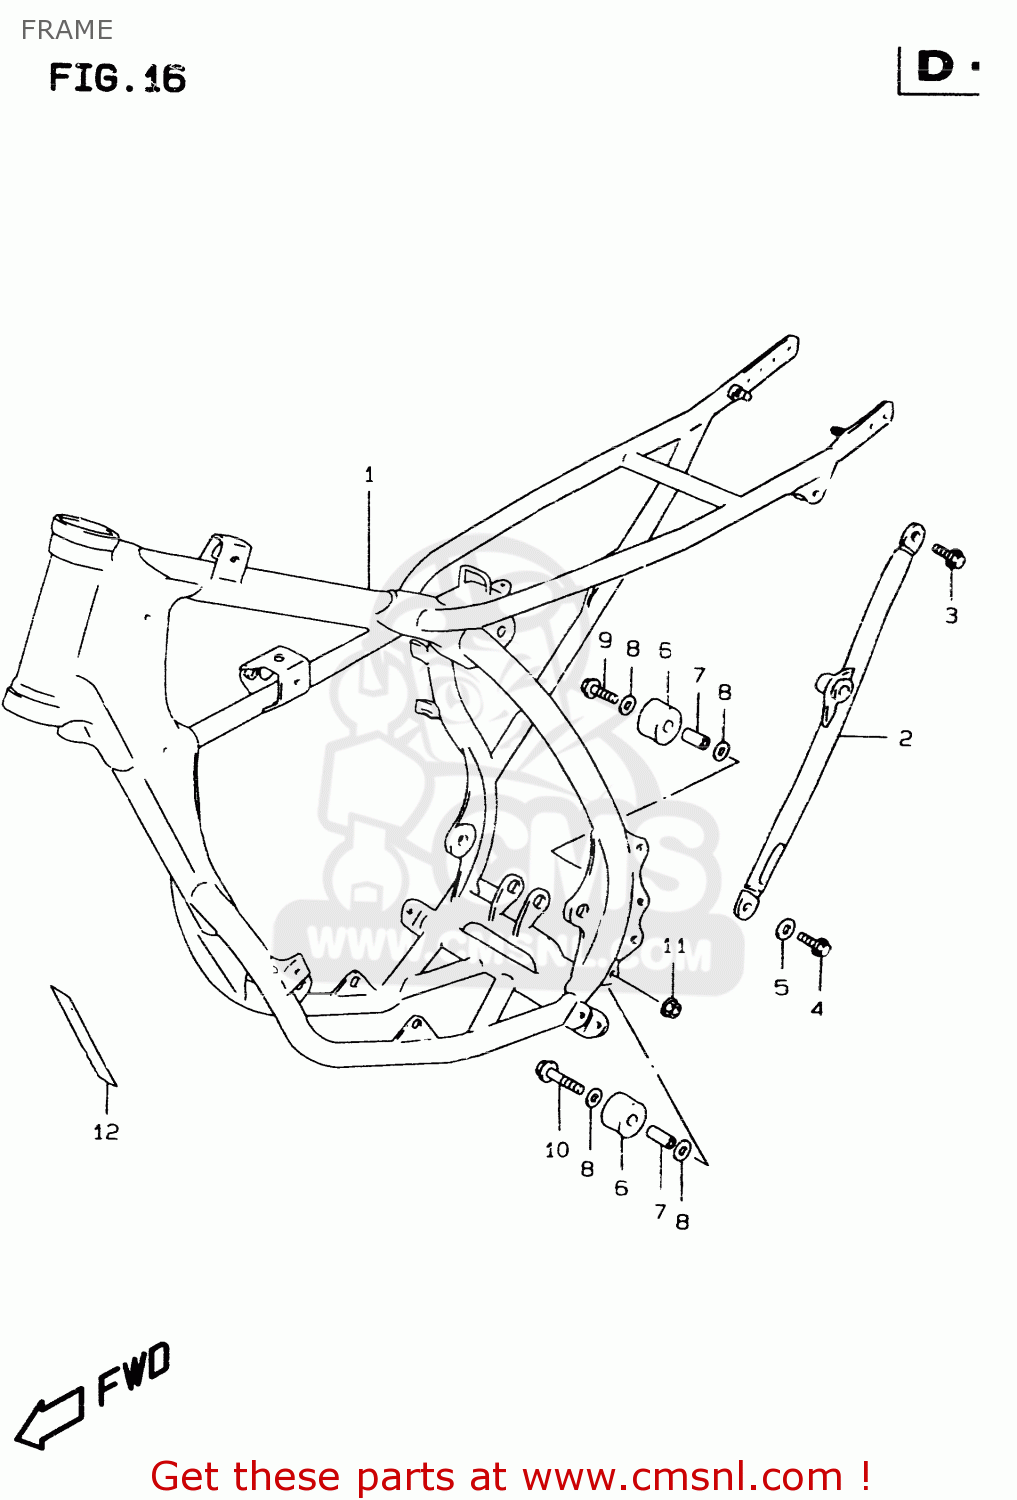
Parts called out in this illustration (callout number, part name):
1	FRAME
2	TUBE,FRAME SIDE(CHARCOAL)
3	BOLT(8X22)
4	BOLT(8X16)
5	WASHER
6	ROLLER,CHAIN CONTROL
7	SPACER(8.6X12X25.5)
8	WASHER
9	BOLT(8X38)
10	BOLT
11	NUT
12	PLATE,WARNING
